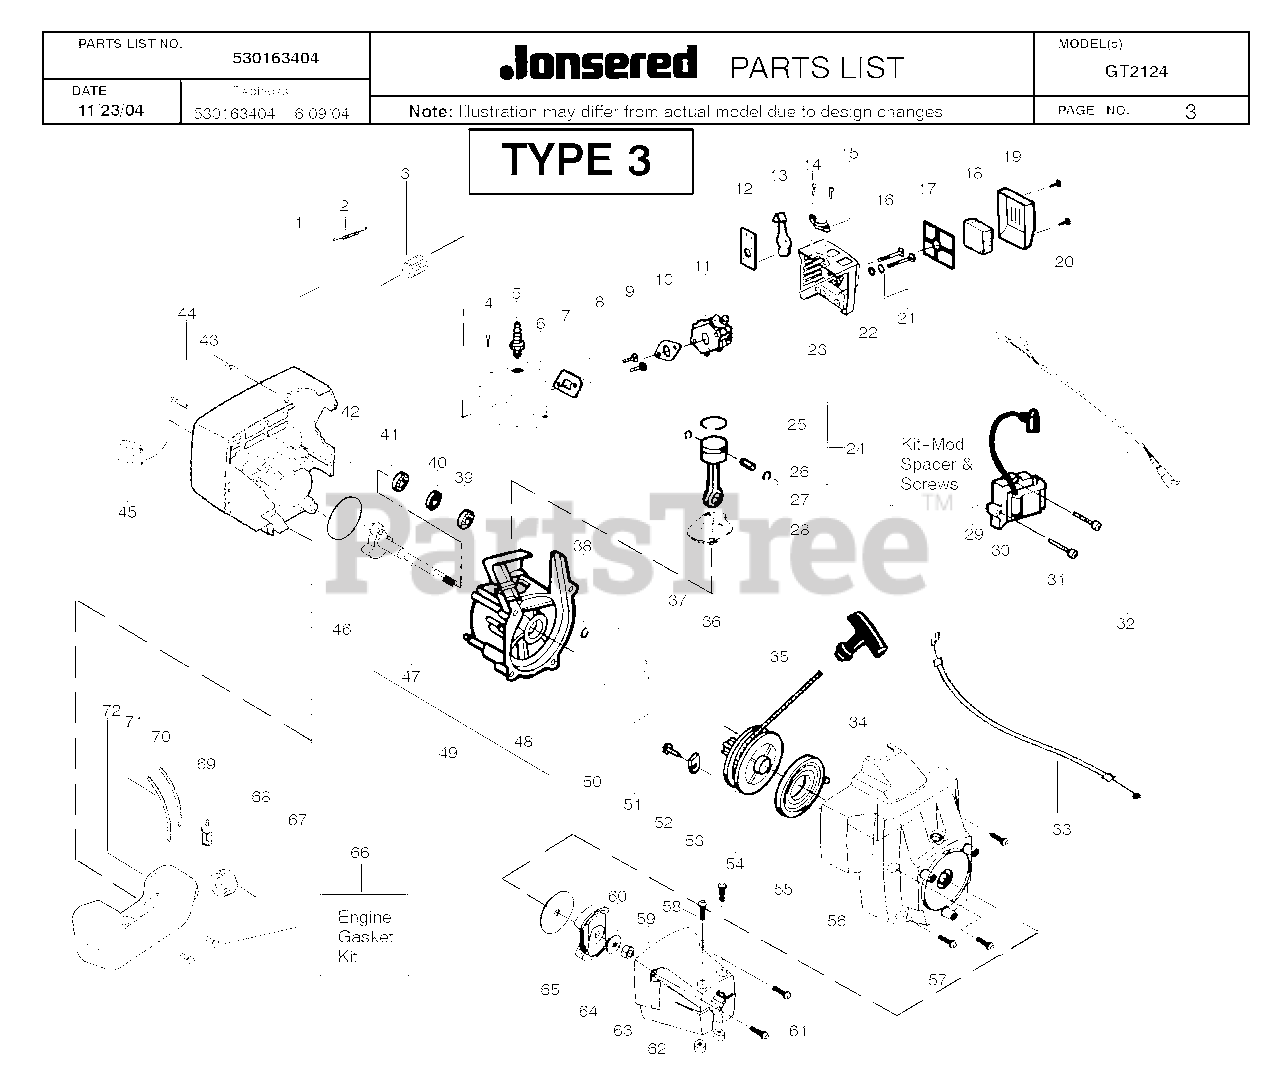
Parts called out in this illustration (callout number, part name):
1	KIT-MUFFLER
5	PLUG-SPARK (RCJ-6Y)
7	GASKET KIT
9	SCREW - CARB. ADAPTOR
10	GASKET KIT
11	CARBURETOR
12	CHOKE PLATE
13	CHOKE SHUTTER
15	AIR PURGE BUBBLE
17	FILTER PLATE
18	AIR FILTER FOAM
19	AIR FILTER COVER
20	SCREW FILTER PLATE
21	CHOKE SPACER
24	PISTON KIT
25	PISTON RING
26	WRIST PIN RET.
28	GASKET KIT
30	IGNITION MODULE
32	LEAD WIRE ASSEMBLY
34	HANDLE-STARTER
36	SCREW SEMS TOOTHED WASHER
38	RETAINING RING
39	OUTER BEARING
40	KIT-CRANKCASE SEAL
41	BEARING
44	SCREW - SHROUD
46	GASKET KIT
47	CRANKSHAFT ASSEMBLY
50	FLYWHEEL
52	SCREW 8-16 X 9/16 (PLAS
54	STARTER PULLEY KIT
55	STARTER SPRING
57	SCREW - SHROUD
58	SCREW-10-24 X 1-3/8 (UN
59	CLUTH COVER
60	WASHER FLAT
61	SCREW-10-14 X 13/16 (PL
62	LOCKNUT-HEX 10-24
64	CLUTCH ASSEMBLY KIT
65	FRICTION DISC,CLUTCH 36/41
66	GASKET KIT
68	CAP ASSY W/ RETAINER
69	FUEL PICK-UP ASSY
